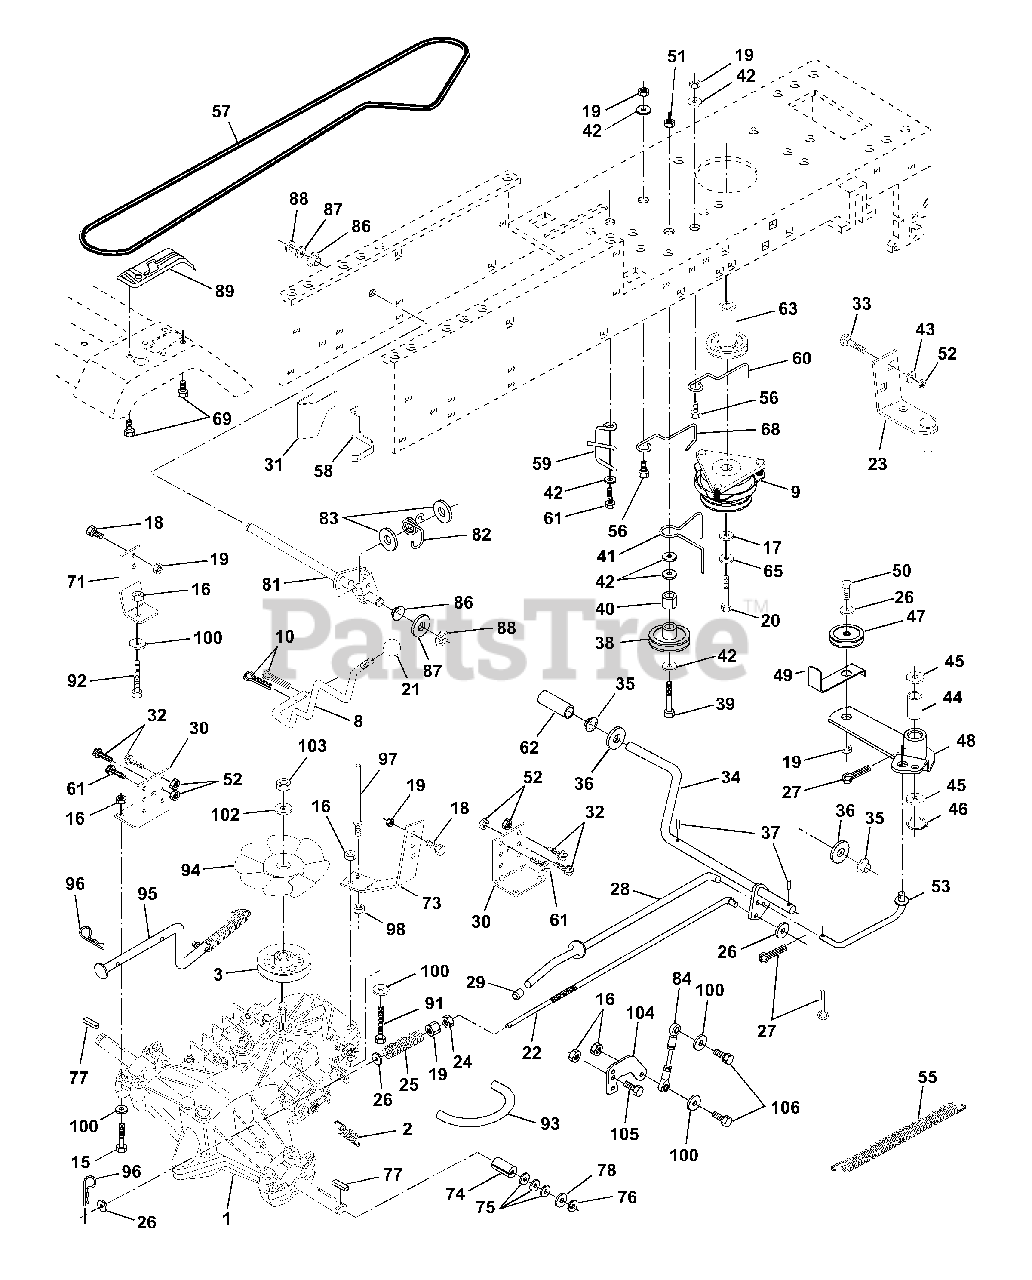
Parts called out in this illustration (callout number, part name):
1	Transaxle Assembly
2	Spring, Return, Brake
3	Pulley, Transaxle
8	Rod Shift Hydro YT
9	Clutch Elecric
10	Pin Cotter 1/8 x 1 CAD
15	Bolt Fin Hex 5/16-18 Unc
16	Nut Lock Hex W/Ins. 5/16-18 Unc P
17	Washer 1-1/2 OD x 15/32 ID x .250
18	Bolt Fin Hex 3/8-16 Unc x 1 Gr.5
19	Nut Lock Hex W/Wsh 3/8-16 Unc
20	Bolt, Hex 7/16-20 x 4-1/4 Ja. 5
21	Knob Deluxe 1/2-13 UNC BLK/BLK
22	Rod, Brake Hydro
23	Bracket Asm Mtg CL
24	Locknut
25	Spring, Brake Rod
26	Washer
27	Pin Cotter 1/8 x 3/4 CAD.
28	Rod, Parking Brake
29	Cap,Parking Brake
30	Bracket, Transaxle
31	Keeper Belt Lh
32	Bolt Hex Hd 5/16-18 Unc x 3/4
33	Bolt Carriage 5/16-18 UNC x 3/4
34	Shaft, Foot Pedal
35	Bearing, Nylon
37	Pin, Roll
38	Pulley, Idler, Flat
40	Spacer Split
41	Keeper, Belt Retainer
42	Washer 13/32 x 13/16 x 12 Gauge
43	Washer 11/32 x 5/8 x 12 Ga.
44	Bearing, Nylon
45	Washer, Hardened
46	Ring, Klip
47	Pulley, Idler, V-Groove
48	Bellcrank Assembly
49	Retainer, Belt
50	Bolt
52	Nut Crown Lock 5/16-18
53	Link, Clutch
55	Spring, Return, Clutch
56	Bolt Fin Hex 3/8-16 Unc x 1-1/4
57	V-Belt, Ground Drive
58	Keeper Belt Lh Hydro 0750.18/20"
59	Keeper, Center Span
60	Keeper Belt Engine
61	Screw Thdrol. 3/8-16 x 3/4 Ty. TT
62	Cover, Pedal
63	Pulley, Engine
65	Washer
68	Keeper Belt Engine
71	Strap Torque Lh Hydro 18/20" T
73	Strap Torque Rh Hydro 18/20" T
74	Spacer, Split
75	Washer 25/32 x 1-1/4 x 16 Gauge
77	Key, Square
78	Washer 25/32 x 1-5/8 x 16 Gauge
81	Shaft Asm. Cross Hydro 20" Tires
82	Spring Torsion T/A
83	Washer 17/32 x 3/4 x 16 Ga.
84	Rod, Tie Hydro 20" Tires
86	Bushing Rod Strig. 629/632 ID
87	Washer 21/32 x 1-1/4 x 16 Ga.
88	Ring Klip #5304-62
89	Console, Shift
91	Bolt Fin Hex 5/16-18 x 2-1/4
92	Bolt Fin Hex 5/16-18 Unc x 1-1/2
93	Line Fuel Hydro 4"
94	Fan, Hydro 7"
95	Control Asm. Bypass Hydro
96	Retainer Spring 1" Zinc/Cad
97	Keeper Belt Rh Hydro 0750.18/20"
98	Nut Keps Hex 3/8-16 Unc
100	Washer 11/32 x 3/4 x 16 Ga.
102	Washer Belleville .501D x 1.50D
103	Nut Hex Jam Toplock 1/2-20 Unf
104	Arm, Control Hydro
105	Screw Cap Hex 5/16 x 18 x 1
106	Bolt Fin Hex 5/16-18 Unc x 1-1/4
